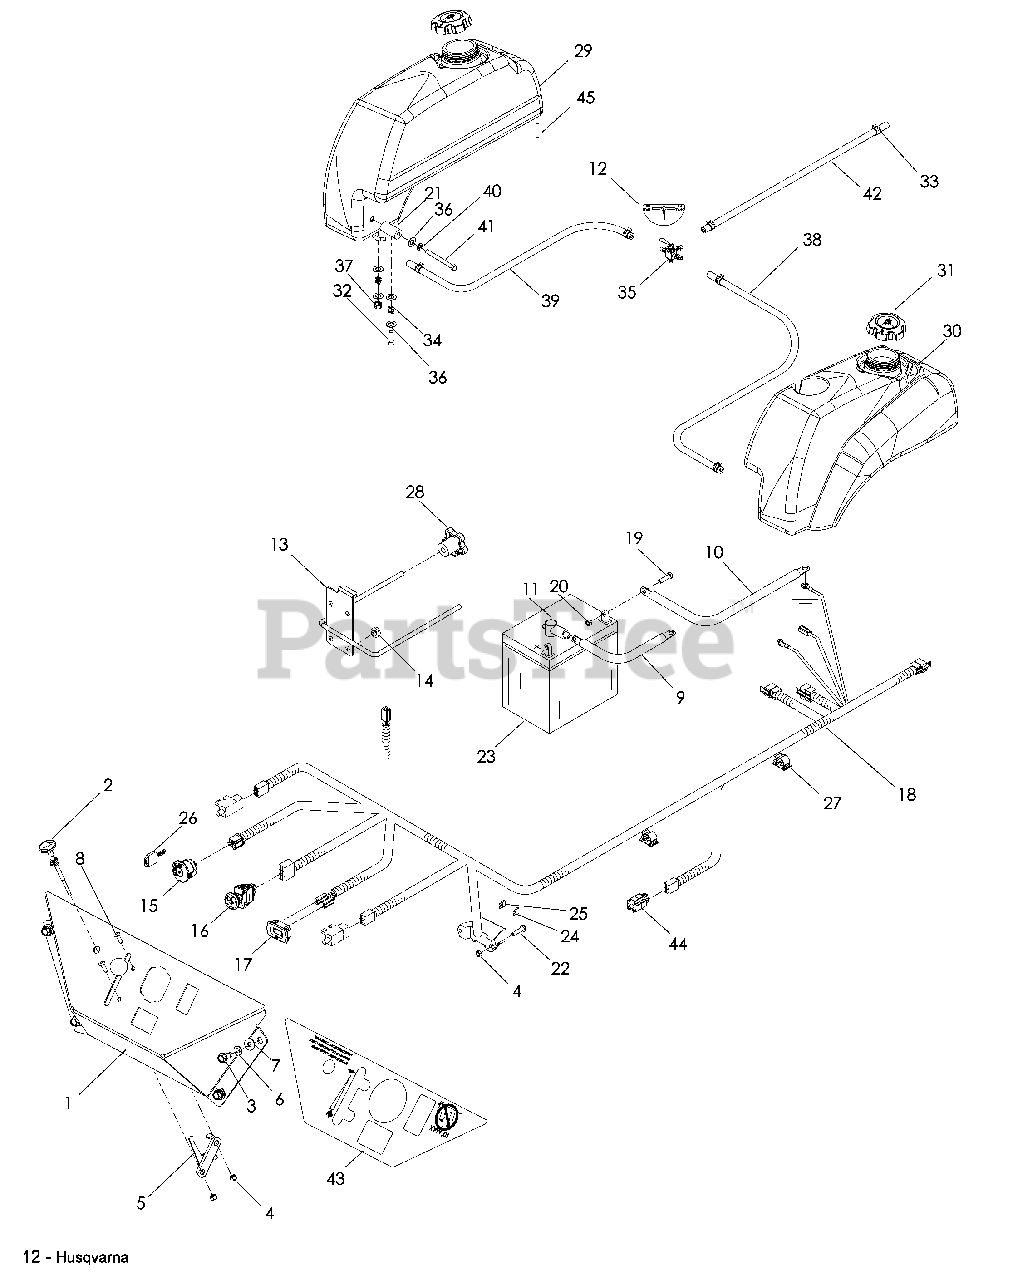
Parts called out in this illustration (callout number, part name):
2	CONTROL, CHOKE
3	SCREW ¼-20 x 5/8 THD FRM
4	NUT 10-24 NYLOC
5	CABLE, THROTTLE
6	LOCKWASHER ¼
7	WASHER ¼ FLAT
8	HCS 10-24 x ½
9	CABLE, POSITIVE
10	CABLE, NEGATIVE
12	DECAL, FUEL LINE
13	HOLD DOWN, BATTERY
15	SWITCH, IGNITION
16	SWITCH, PTO
17	METER, HOUR
18	HARNESS, FRAME
19	HCS 5/16-18 x ¾
20	NUT 5/16-18 HEX NYLOC
21	SPACER, TANK
22	SCREW 10-24 x 7/8
23	BATTERY, DRY
24	FUSE, 7.5 AMP 32V ATO
25	FUSE, 20 AMP 32 V ATO
26	KEY, PADDED
27	CLIP, PUSH MOUNT WIRE
29	FUEL TANK RT
30	FUEL TANK LT
32	HCS 5/16-18 x 1
33	CLAMP, HOSE
35	VALVE, FUEL
36	WASHER 5/16 STD FLT
37	NUT 5/16-18 CNTRLK
38	LINE, FUEL
39	LINE, FUEL
40	WASHER 5/16 SLW
41	HCS 5/16 x 4
42	LINE, FUEL
43	DECAL, CONSOLE
44	SWITCH, BRAKE
45	STUD, FUEL TANK
